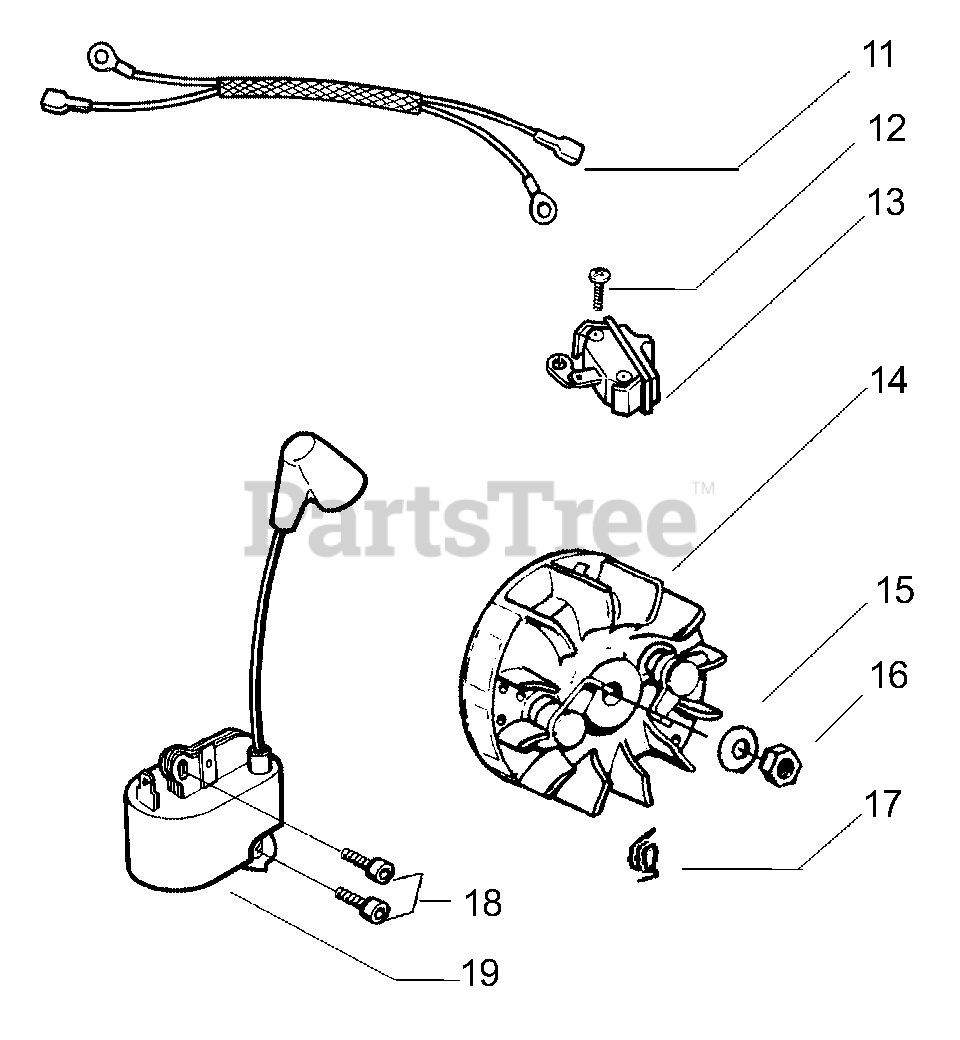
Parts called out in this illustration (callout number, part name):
11	Leadwire Harness Ass'y.
13	Ignition Switch
14	Assy. Flywheel
15	Flywheel Washer
17	Spring - Starter Dog
19	Module - Ignition
